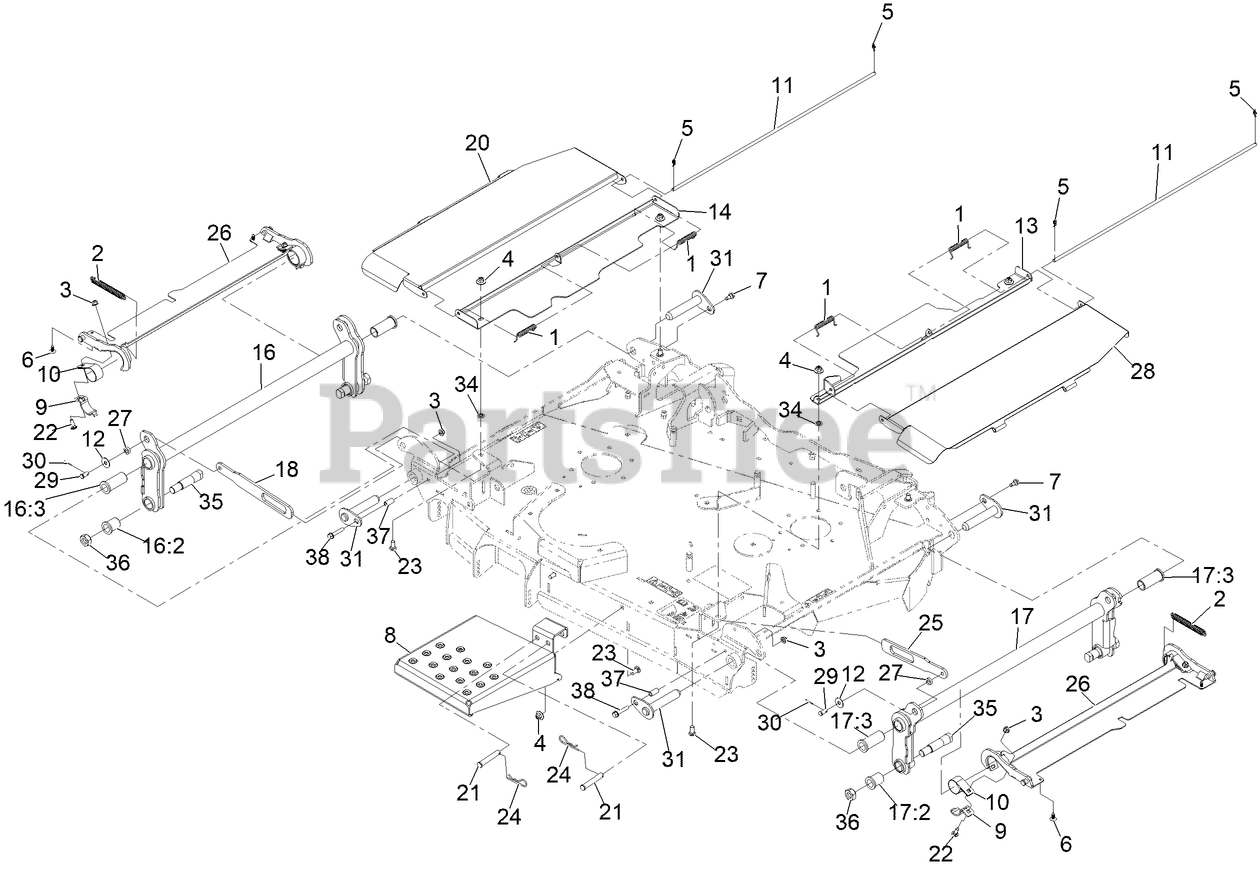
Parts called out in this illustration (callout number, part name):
1	SPRING-TORSION
3	NUT-HF, NI
4	Nut-Nyloc 3/8-16 Flg
5	PIN-COTTER, LOCKING
6	PLUG-PLASTIC
7	SCREW-SHOULDER
8	PLATE-DECK STEP
9	PLATE-RETAINER, BEARING
10	BEARING-STRAP, NYLON
11	COVER-ROD, PIVOT
13	SHIELD-CENTER, LH
14	SHIELD-CENTER, RH
16	ASM-RH FOLD ARM
16:2	BUSHING-FLANGED
16:3	BUSHING-FLANGED
17	ASM-LH FOLD ARM
17:2	BUSHING-FLANGED
17:3	BUSHING-FLANGED
18	STRAP-RH FLAG
20	Panel-Shield Hinge, LH
21	PIN-CLEVIS
22	SCREW-CARR
23	BOLT-CARR
24	PIN-HAIR
25	STRAP-LH FLAG
26	ASM-WING COVER, [RED]
27	BUSHING
28	Shield-Center, RH
29	PIN-CLEVIS
30	Pin-Cotter
31	ASM-DECK PIN
34	NUT-PUSH
35	BOLT-PIVOT PIN
36	NUT-LUG
37	Tube-Standoff
38	Screw-HWH
